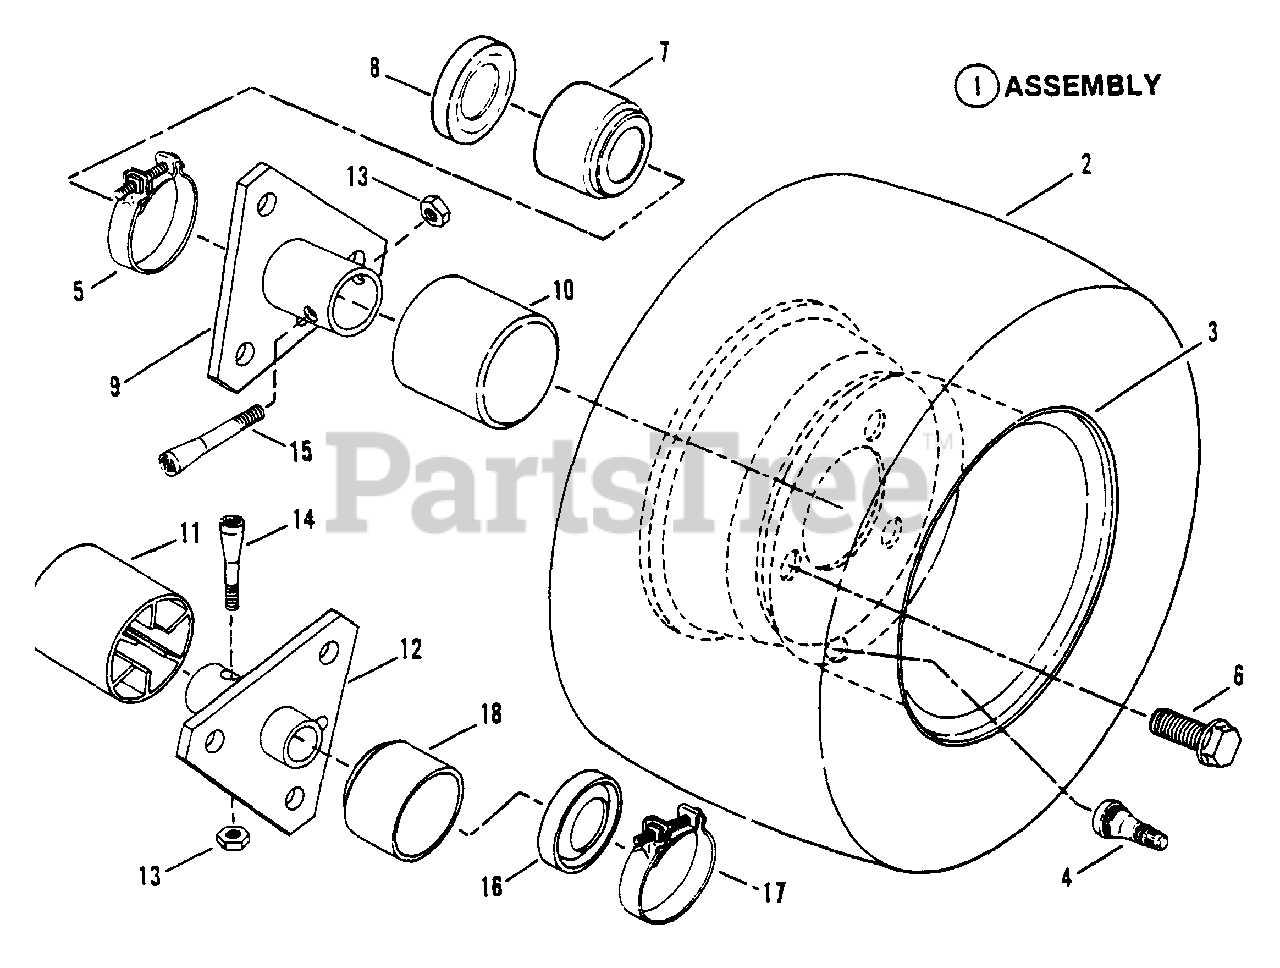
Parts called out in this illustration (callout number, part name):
1	ASSEMBLY, Rear Tire 8 Rim
2	TIRE, Ext Wide, 16/7.50 x 8
3	RIM, Ext Wide,
4	VALVE, Air (Snap-in)
5	CLAMP, Right Hand
6	BOLT, 1/2-20 x 3/4" Lug
7	BOOT, Right Hand
8	SEAL, Oil
9	HUB, Rear Wheel (Right Hand)
10	CAP, Hub
11	CAP, Hub (Left Hand)
12	HUB, Rear Wheel
13	NUT, 5/16-24 Hex Center Lock
14	BOLT, 5/16-24 x 1-5/8" Tapered (Left Hand)
15	BOLT, 5/16-24 x 2" Tapered (Right Hand)
16	SEAL, Oil (Left Hand)
17	CLAMP, (Left Hand)
18	BOOT, (Left Hand)
